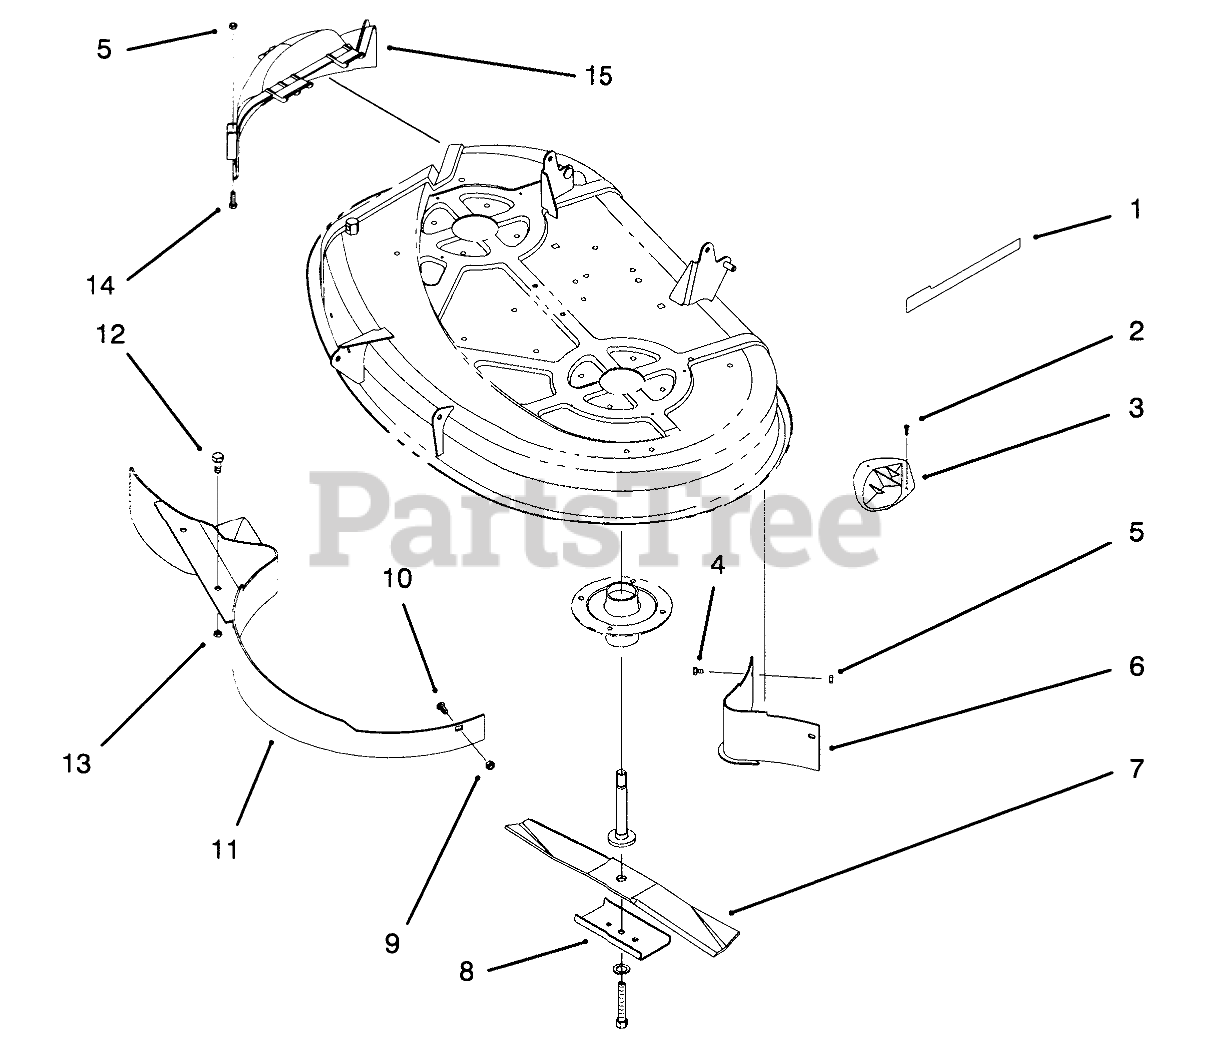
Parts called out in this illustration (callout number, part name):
1	DECAL-RECYCLER
2	SCREW-PPH
3	PLATE-KICKER
4	SCREW-HH
5	NUT-LOCK, NI
6	Baffle-Rear
7	BLADE KIT
8	Stiffener
9	NUT-LOCK, NI
10	BOLT-CARR
11	Baffle-38"
12	SCREW-HH
13	NUT-LOCK, NI
14	SCREW-HH
15	COVER-RECYCLER
